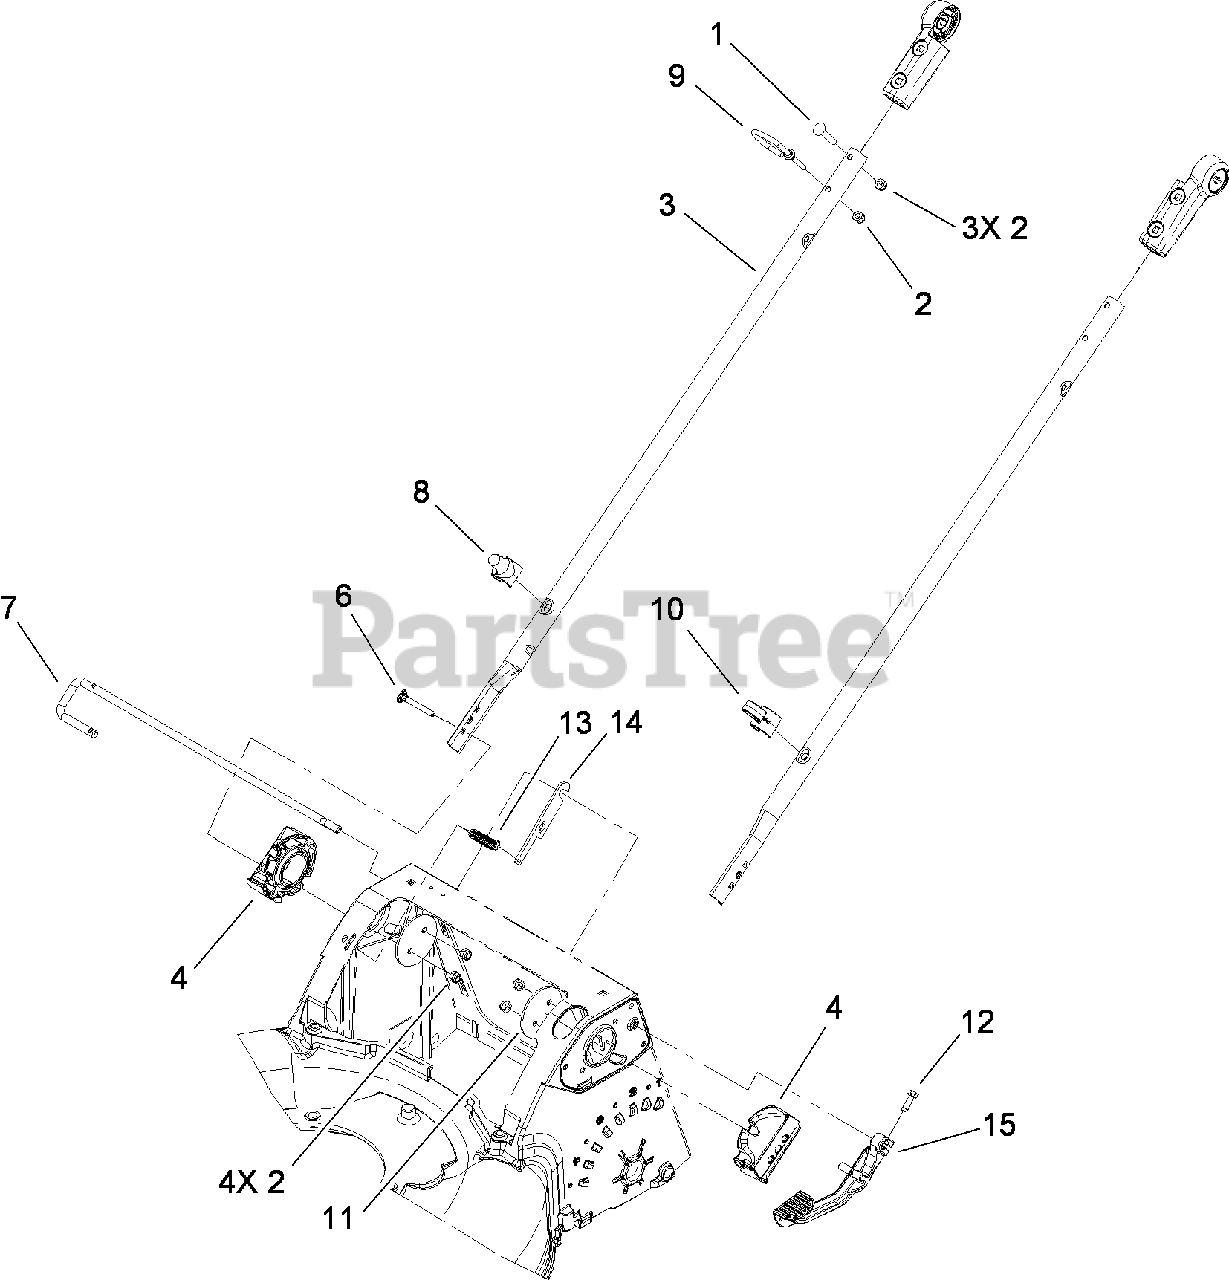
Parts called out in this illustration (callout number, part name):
1	SCREW-CARR
2	NUT-LOCK, NI
4	HANDLE-MOUNT, LOWER
7	ROD-HANDLE RELEASE
8	GUIDE-ROPE, LOWER
9	GUIDE-ROPE, UPPER
10	Guide-Cable
12	SCREW-HWHTF
13	SPRING-EXTENSION
14	PLATE-RELEASE ROD
15	LEVER-RELEASE
